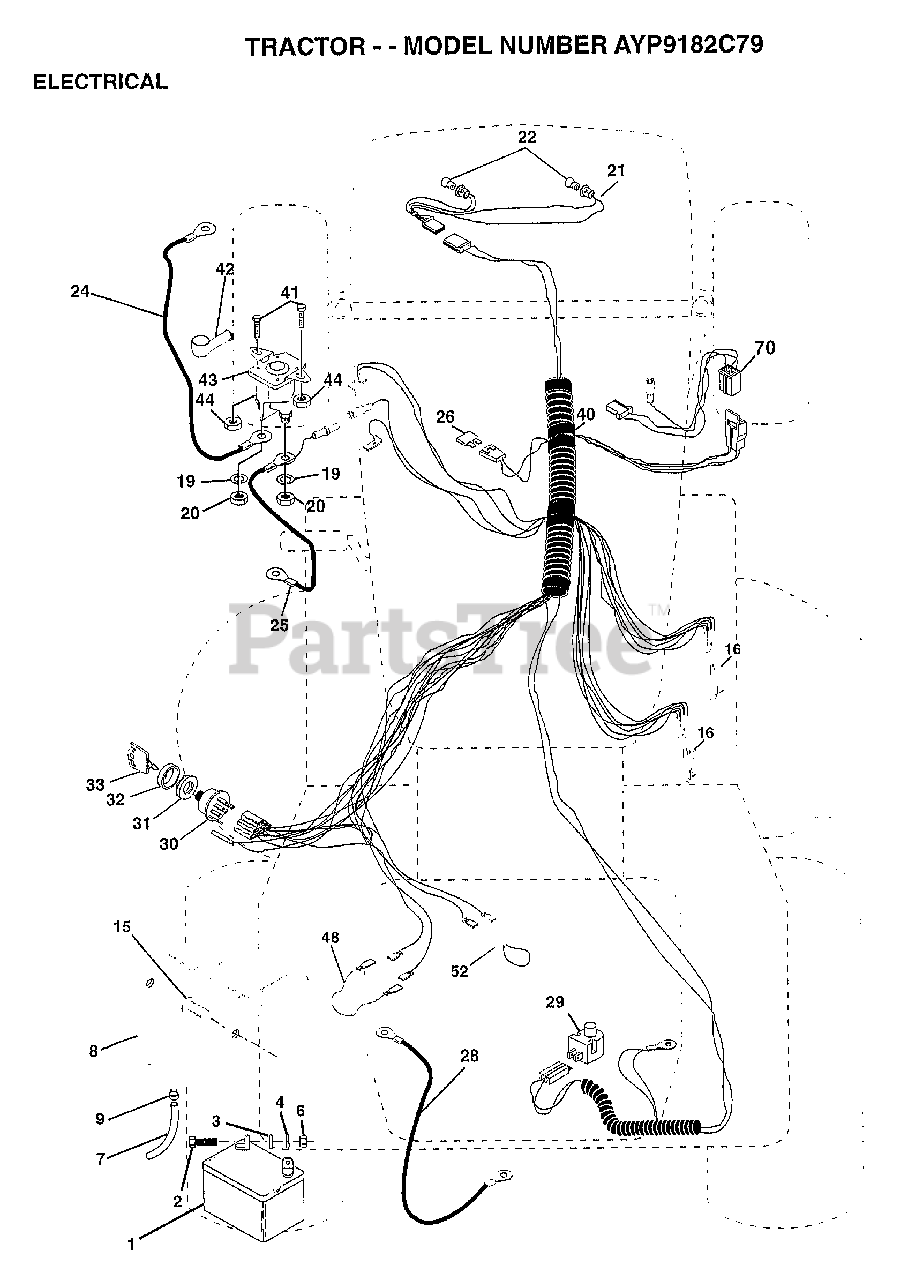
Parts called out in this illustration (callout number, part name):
2	BOLT LT
3	WASHER
4	LOCKWASHER
7	TUBE T
8	"CASE,BATTERY.MECH"
9	HOSE CLAMP T
15	FASTNER.SNAP-IN
16	SWITCH INTERLOCK
20	NUT
21	"HARNESS,LIGHT SOC"
22	HEADLAMP BULB
24	"CABLE T, BATTERY"
25	CABLE.BTRY.6GA.RD
26	FUSE HYT
28	CABLE T
29	SWITCH SEAT
30	SWITCH IGN 4POS
31	NUT IGNITION
32	COVER KEY SWITCH
33	KEY
40	HARNESS-IGNITION
41	BOLT HXHD FIN
44	NUT HXKEP 1/4X20
48	ADAPTER AMMETER
52	PROTECTION LOOP
70	HARNESS ENG DUAL
